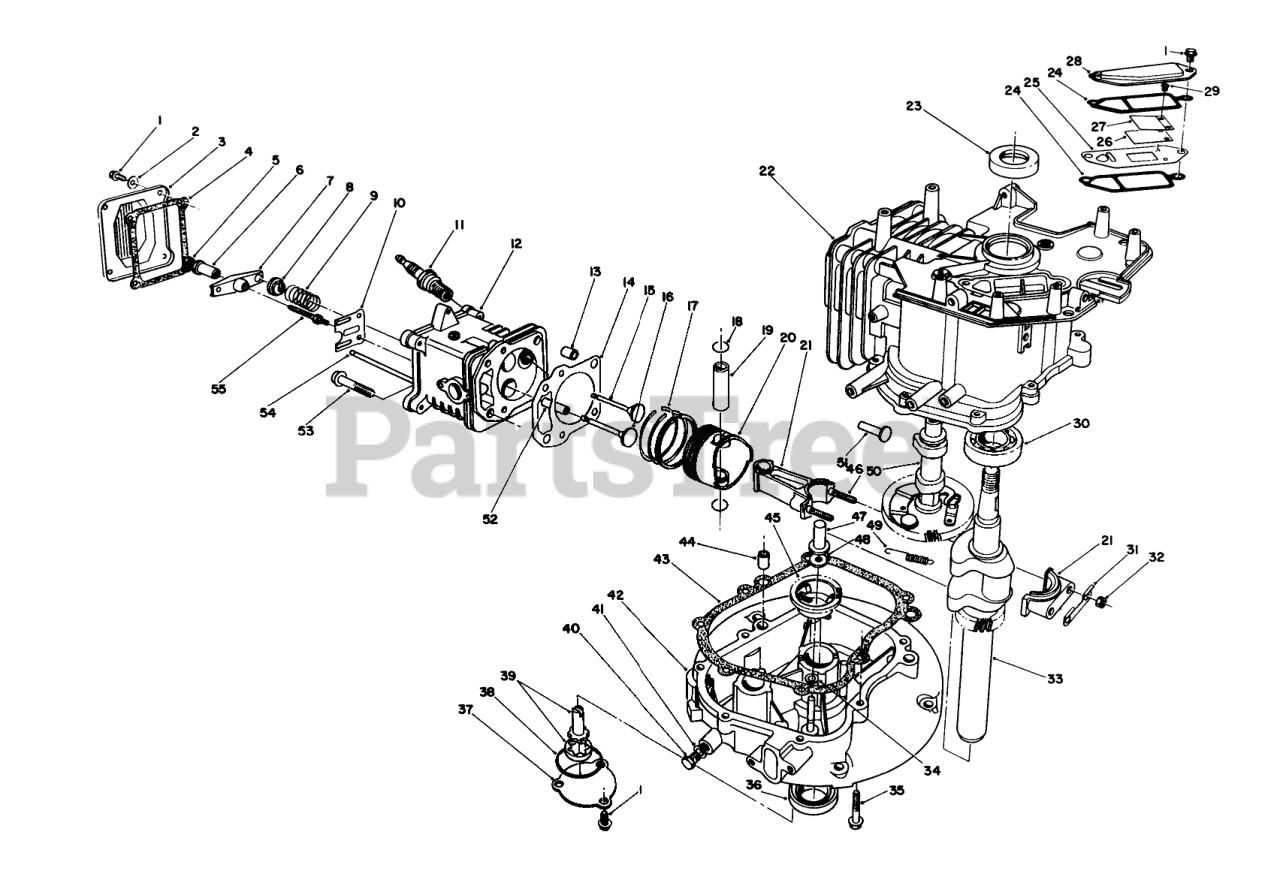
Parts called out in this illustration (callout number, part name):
2	WASHER
3	COVER
4	GASKET
6	PIVOT
8	RETAINER
9	SPRING
10	GUIDE
11	SPARK PLUG
12	Head-Cylinder (Incl. Ref. #52)
14	GASKET
15	VALVE-INTAKE
16	VALVE-EXHAUST
17	RING SET
18	CIRCLIP
20	PISTON
21	Connection Rod Assembly (Incl. Ref. #31, 32, & 46)
22	Block-Engine (Incl. Ref. #23, & 30)
24	GASKET
25	Plate-Breather
26	Valve-Reed
27	Retainer-Reed Valve
28	COVER
29	Screw-Reed Valve
30	BEARING
31	Plate-Lock
33	CRANKSHAFT
34	WASHER
37	COVER
38	O-RING
39	OIL PUMP
40	OIL DRAIN PLUG
41	GASKET
42	Crankcase
43	GASKET
45	GOVERNOR FLYWEIGHT ASM
47	PLUNGER
48	WASHER
49	SPRING
50	Camshaft Assy. (Incl. Ref. #49)
51	TAPPET
52	GUIDE
